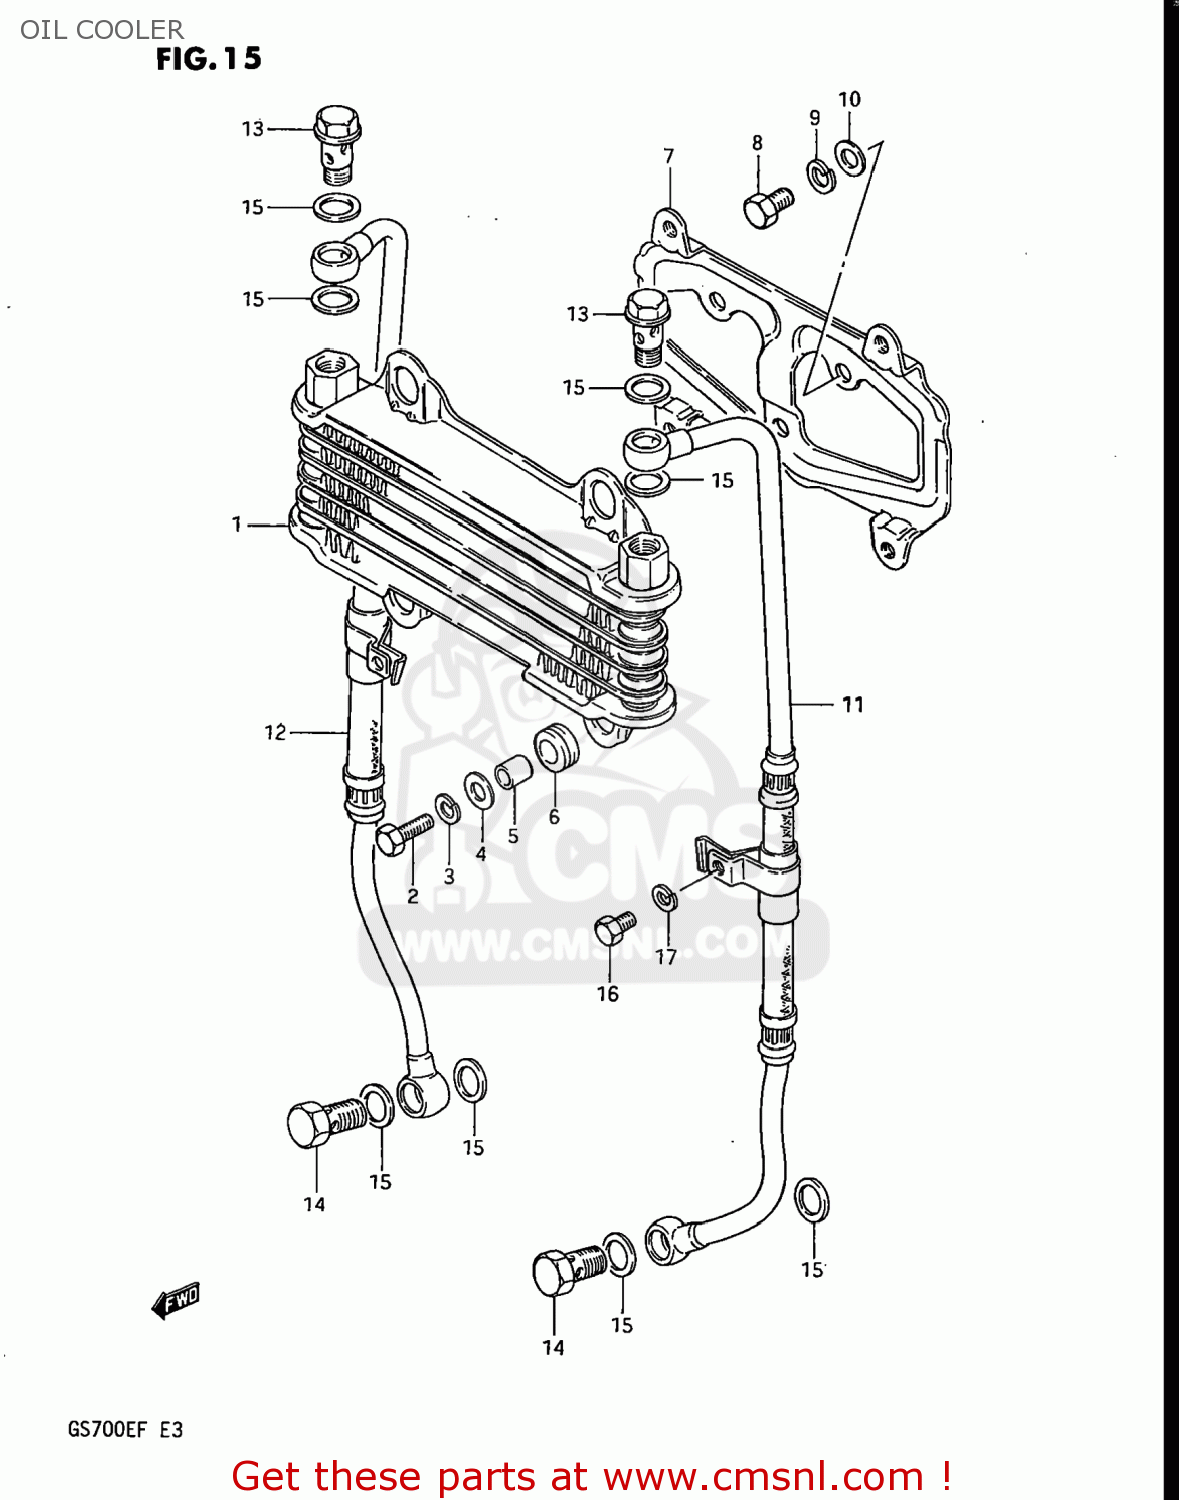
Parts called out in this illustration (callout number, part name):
1	COOLER ASSEMBLY,ENGINE OIL
2	BOLT
3	WASHER,LOCK
4	WASHER (6.5X18X1.6)
5	SPACER (6.8X10X10)
6	CUSHION
7	BRACKET,OIL COOLER
8	BOLT
9	WASHER,LOCK,8.
10	WASHER
11	HOSE,ENGINE OIL,LEFT
12	HOSE,ENGINE OIL,RIGHT
13	BOLT UNION
14	BOLT UNION
15	GASKET(14X20X1.5) (NAS)
16	BOLT
17	WASHER,LOCK
